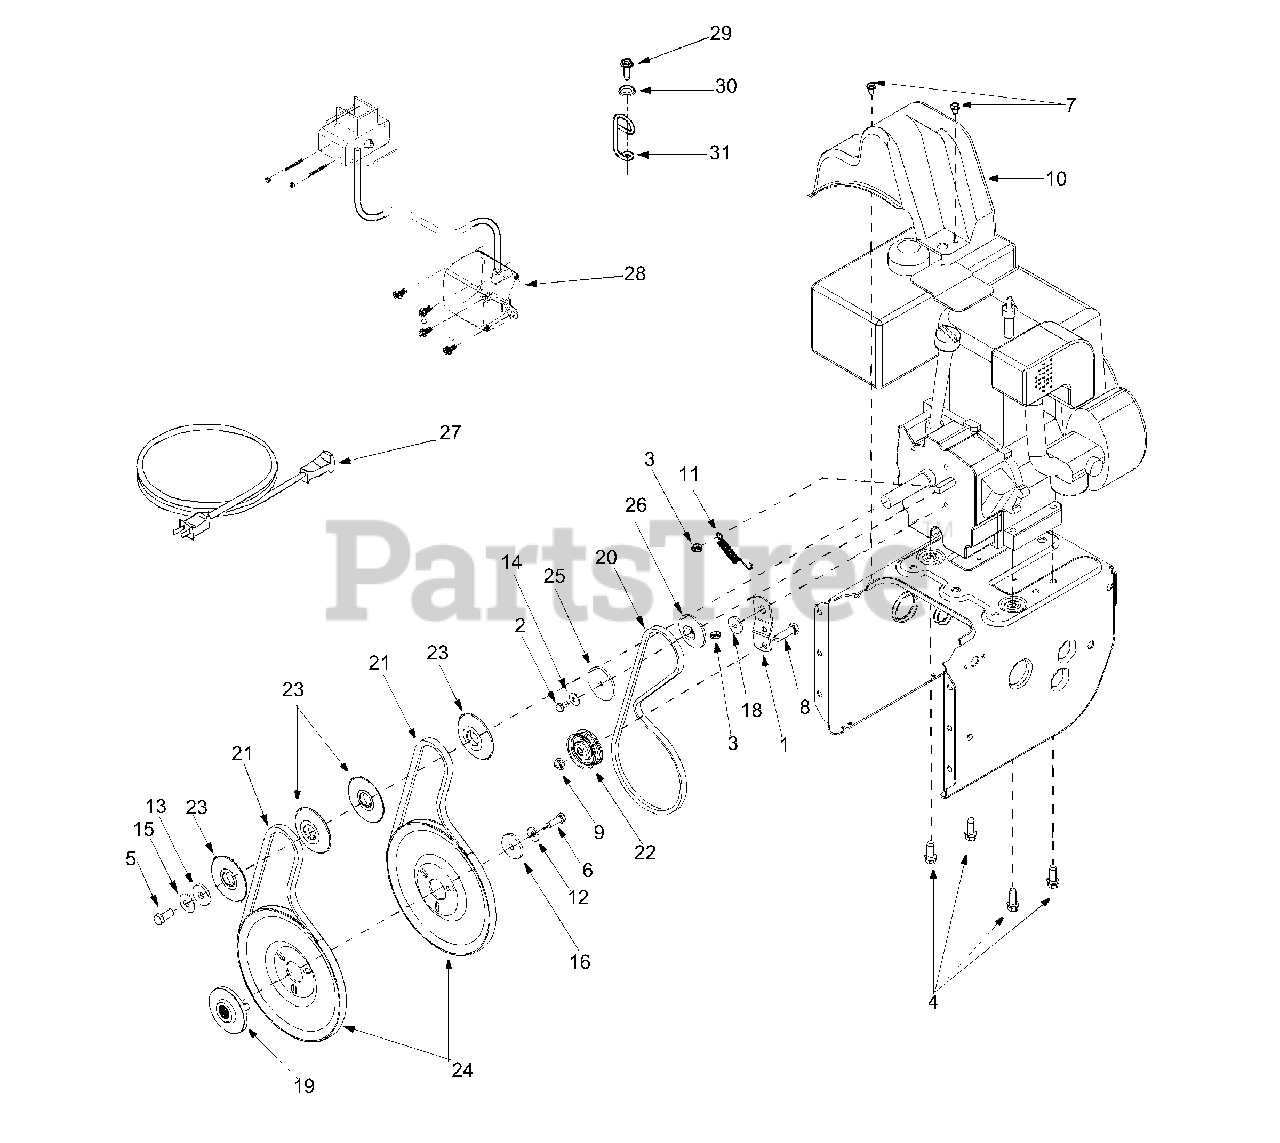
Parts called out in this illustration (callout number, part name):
3	Hex Scr w/ Patch: 5/16-24 x 0.75"
4	Hex Washer Head Sems Screw
5	Hex Bolt 3/8-24 x .875" Gr.8
6	Hex Scr w/ Patch: 5/16-24 x .875"
7	Hex Washer Head TT
8	Hex Screw: 3/8-16 x 1.0"
9	Top Lock Jam Nut: 3/8-16
10	Belt Cover
11	Extension Spring
12	Bellevile Washer
13	Flat Washer
14	Bell Washer
15	Bell Washer
16	Flat Washer
18	Shoulder Spacer
19	Adapter Pulley
20	V-Belt
21	Belt
22	Flat Idler
23	Pulley Half
24	Auger Pulley
25	Pulley Half
26	Pulley Half
27	Extension Cord
28	Electric Start Kit
29	Lock Nut 1/4-20
30	Flat Washer .28 ID x .74 OD
31	Cable Guide
